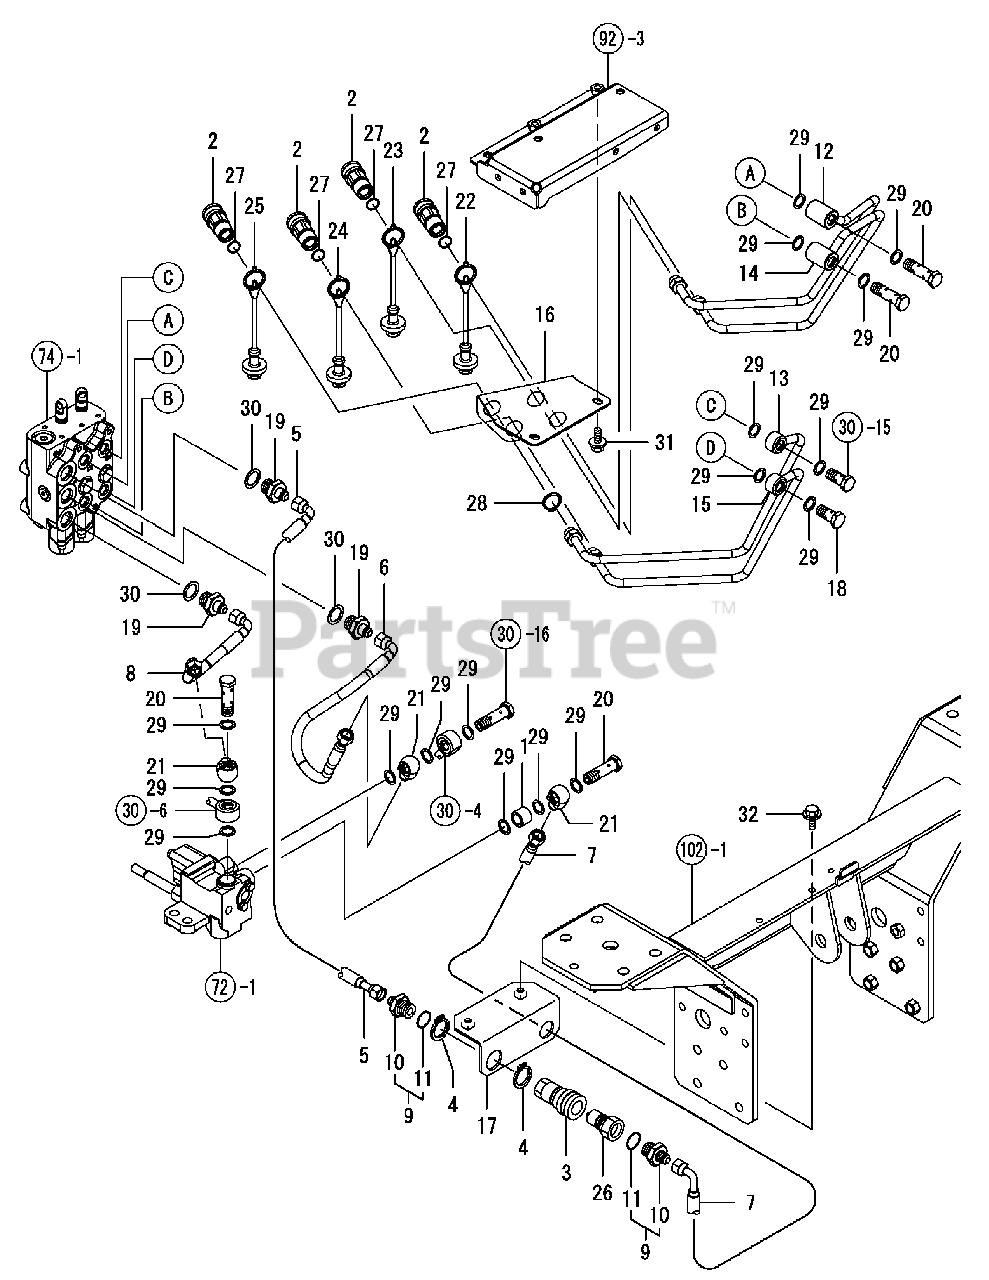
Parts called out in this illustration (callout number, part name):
2	COUPLER, HYD.QUICK
3	COUPLER, QUICK 3/8F
7	HOSE, HP. BH T
10	JOINT, 3/4UNF-9/16UNF
11	O-RING, 8-1
12	HP PIPE CMP, SCV A1
13	HP PIPE CMP, SCV A2
14	HP PIPE CMP, SCV B1
15	HP PIPE CMP, SCV B2
16	STAY(SCV COUPLER
17	STAY ASSY, BH COUPLER
18	BALL JOINT BOLT 9/16
19	JOINT, 3/4UNF-9/16UNF
20	BALL JOINT BT L 9/16
21	JOINT, 9/16UNF-14.5
22	PLUG, DUST RED
23	PLUG, DUST BLUE
24	PLUG, DUST YELLOW
25	PLUG, DUST GREEN
26	COUPLER, QUICK 3/8M
29	GASKET, 14 X 1.0
30	GASKET, 19 X 1.0
